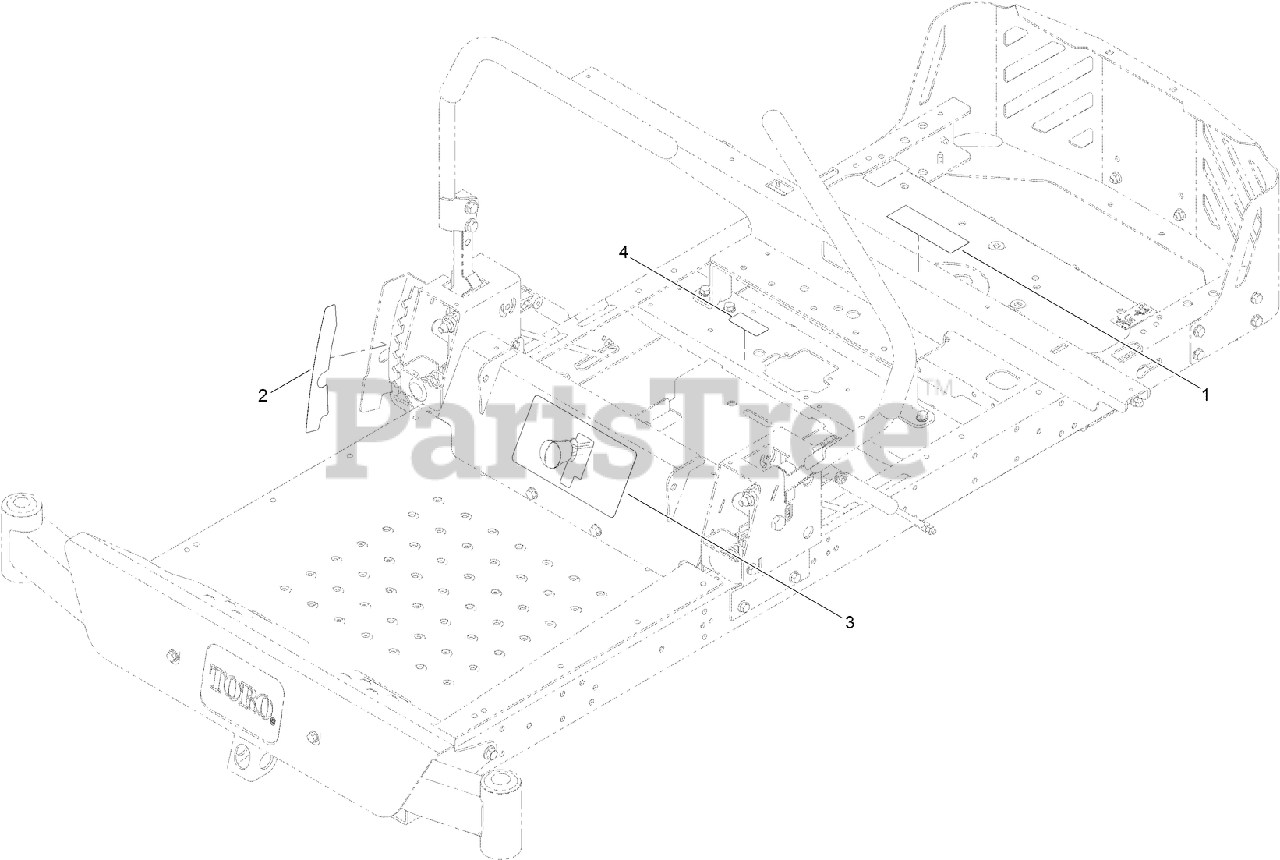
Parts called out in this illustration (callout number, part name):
1	DECAL-SERVICE, CE
2	DECAL-HOC
3	DECAL-CONTROL, SPEED
4	DECAL-LOCATION, SERVICE DEALER
